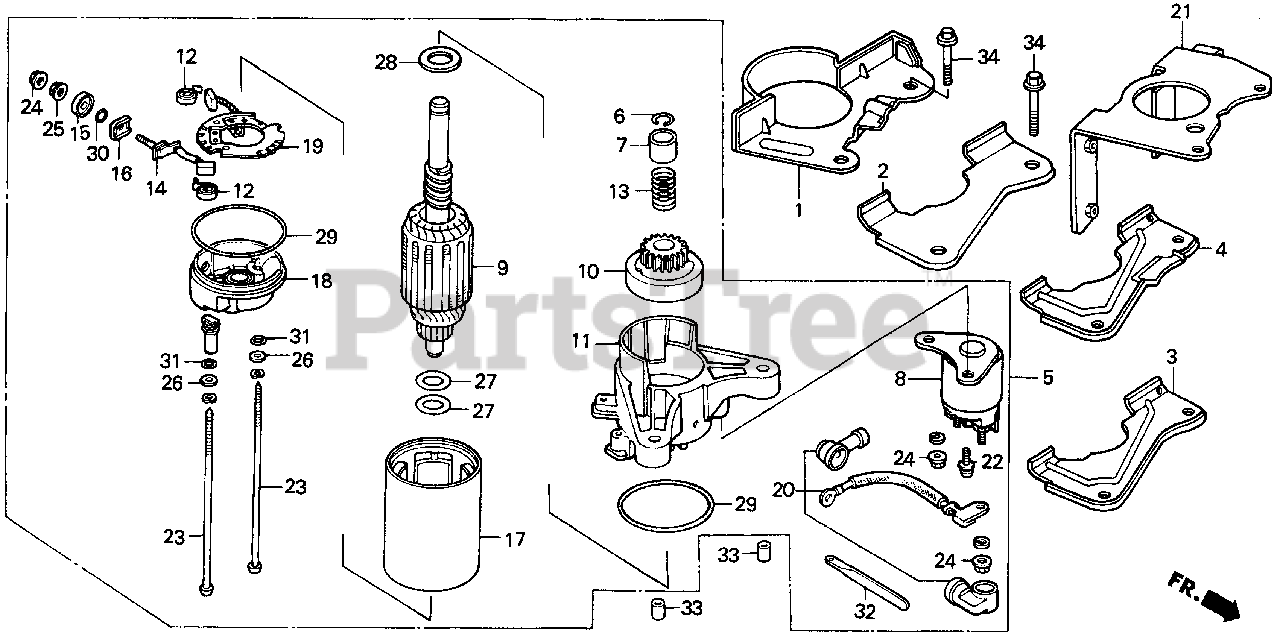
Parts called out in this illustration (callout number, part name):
3	PLATE, SIDE
4	PLATE, SIDE
5	MOTOR ASSY., STARTER
6	RING, SNAP
7	COLLAR, CLUTCH
8	CONTACTOR ASSY.
9	ARMATURE
10	CLUTCH, OVERRUNNING
11	HOUSING, DRIVE SIDE
12	SPRING, BRUSH
13	SPRING
14	BRUSH
15	BUSHING, INSULATION
16	BUSHING, INSULATION
17	YOKE
18	FRAME, STARTER END
19	PLATE, BRUSH HOLDER
20	WIRE, WATER COVER
22	BOLT
23	BOLT, THROUGH
24	NUT
25	NUT
26	WASHER, STEEL PLATE
27	WASHER
28	WASHER
29	O-RING
30	O-RING
31	O-RING
32	CLAMP, WIRE
33	PIN A, DOWEL (10X16)
34	BOLT, FLANGE (8X35)
